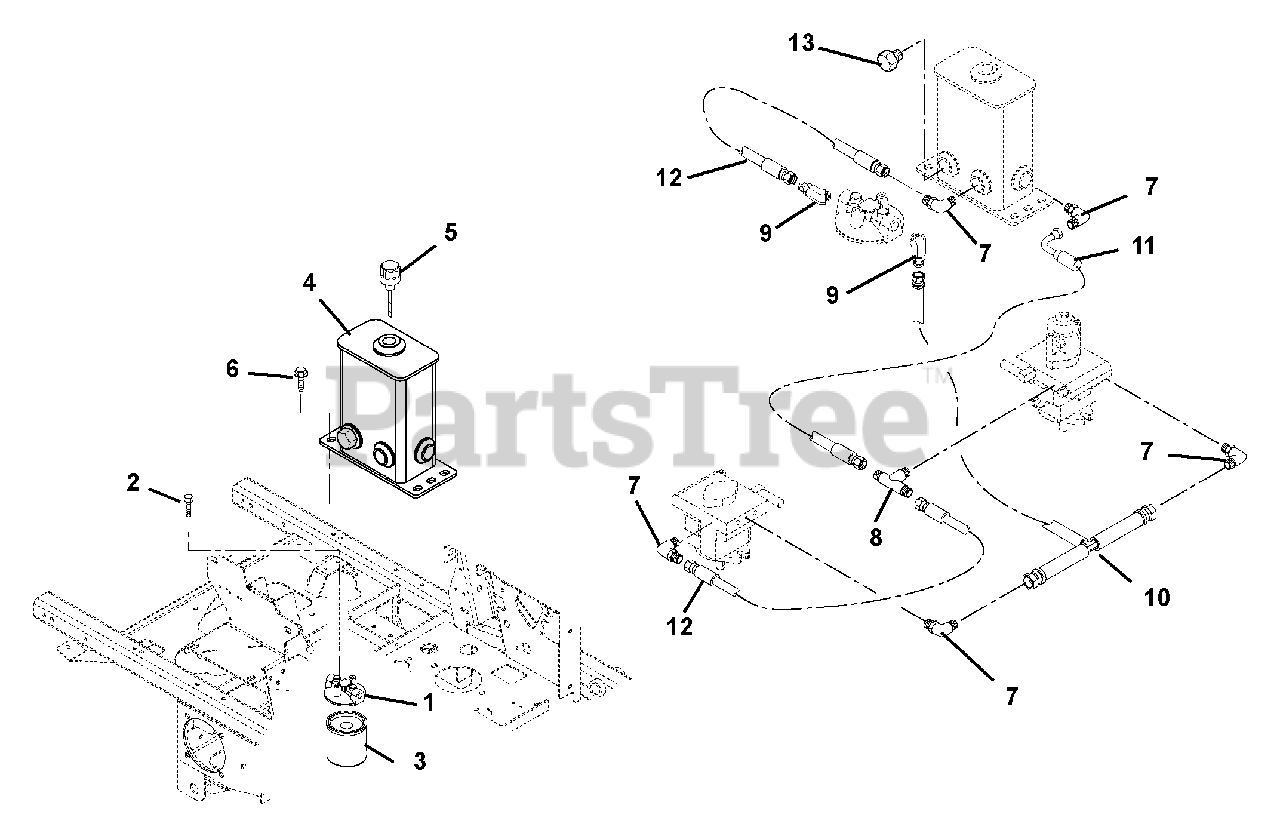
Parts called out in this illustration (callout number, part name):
1	Head, Filter
2	Bolt, Hex .25-20 x .50 Epoxy Grade 5
3	Oil Filter
4	Weldment, Hydraulic Tank
5	Hydraulic Tank Dipstick
6	Screw, Tapping .38-16 x .75 Hex Washer Head
7	Fitting, Hydraulic, 90 Degree Elbow, Steel M8F-M80
8	Fitting, Hydraulic Tee M80-M80-M80
9	Fitting, Hydraulic 45° M80-M120
10	Hose, Tee Assembly, .50
11	Hose, Hydraulic
12	Hose, Hydraulic
13	Plug, Hex, .75-16 O-Ring
